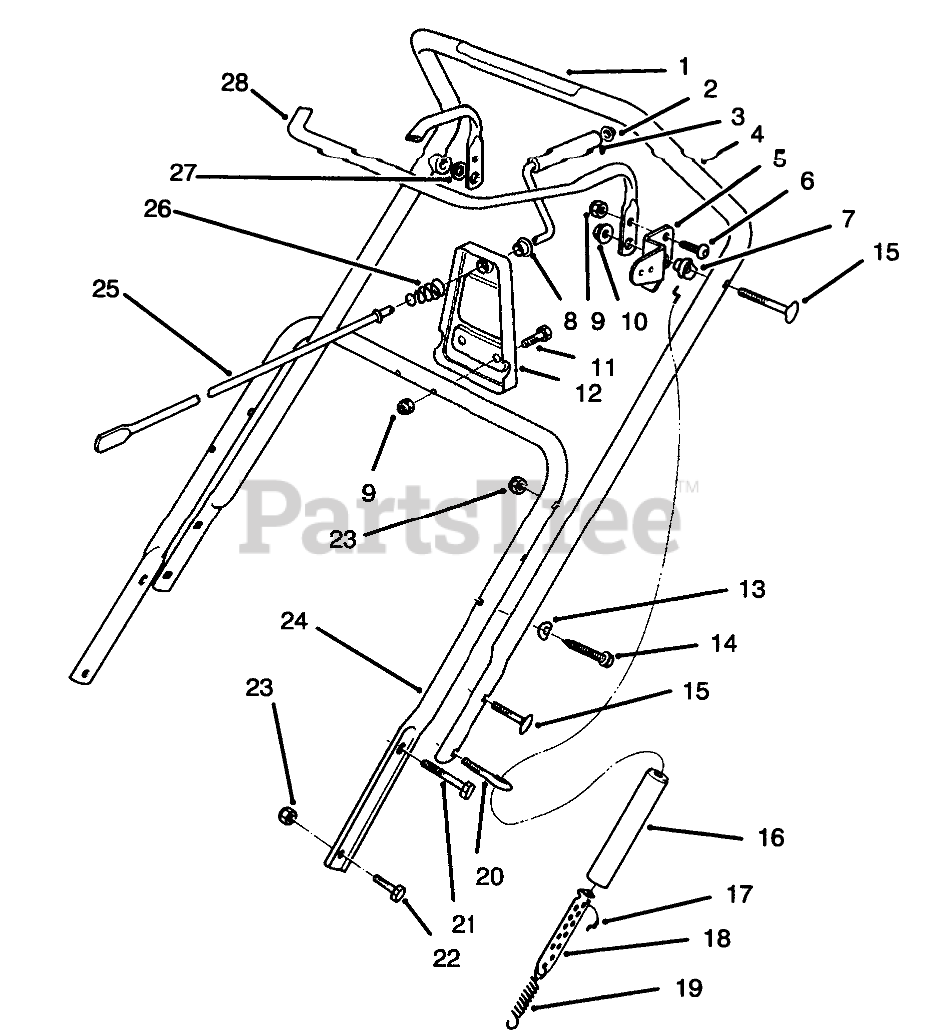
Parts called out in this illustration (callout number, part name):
1	DECAL - ROTOR DRIVE
2	RETAINER-PUSH ON
3	GRIP-CONTROL, CHUTE
4	Upper Handle Assembly (Incl. Ref. #1, Model 38180)
5	Arm-Clutch Cable
6	SCREW-HSBH
7	SPACER-BAR, CONTROL
8	NUT-LOCK, CAP
9	NUT-LOCK, NI
10	Bushing
11	SCREW-HH
12	Support-Crank
13	WASHER
14	SCREW
15	SCREW
16	COVER-SPRING
17	CABLE-CLUTCH
18	ADJUSTER-CABLE
19	SPRING-EXTENSION
20	BOLT-EYE
21	SCREW-HH
22	SCREW-HH
23	NUT-LOCK, NI
24	Handle-Lower (Model 38180)
25	ROD-CRANK, CHUTE
26	SPRING-COMPRESSION
27	WASHER
28	Bar-Control
